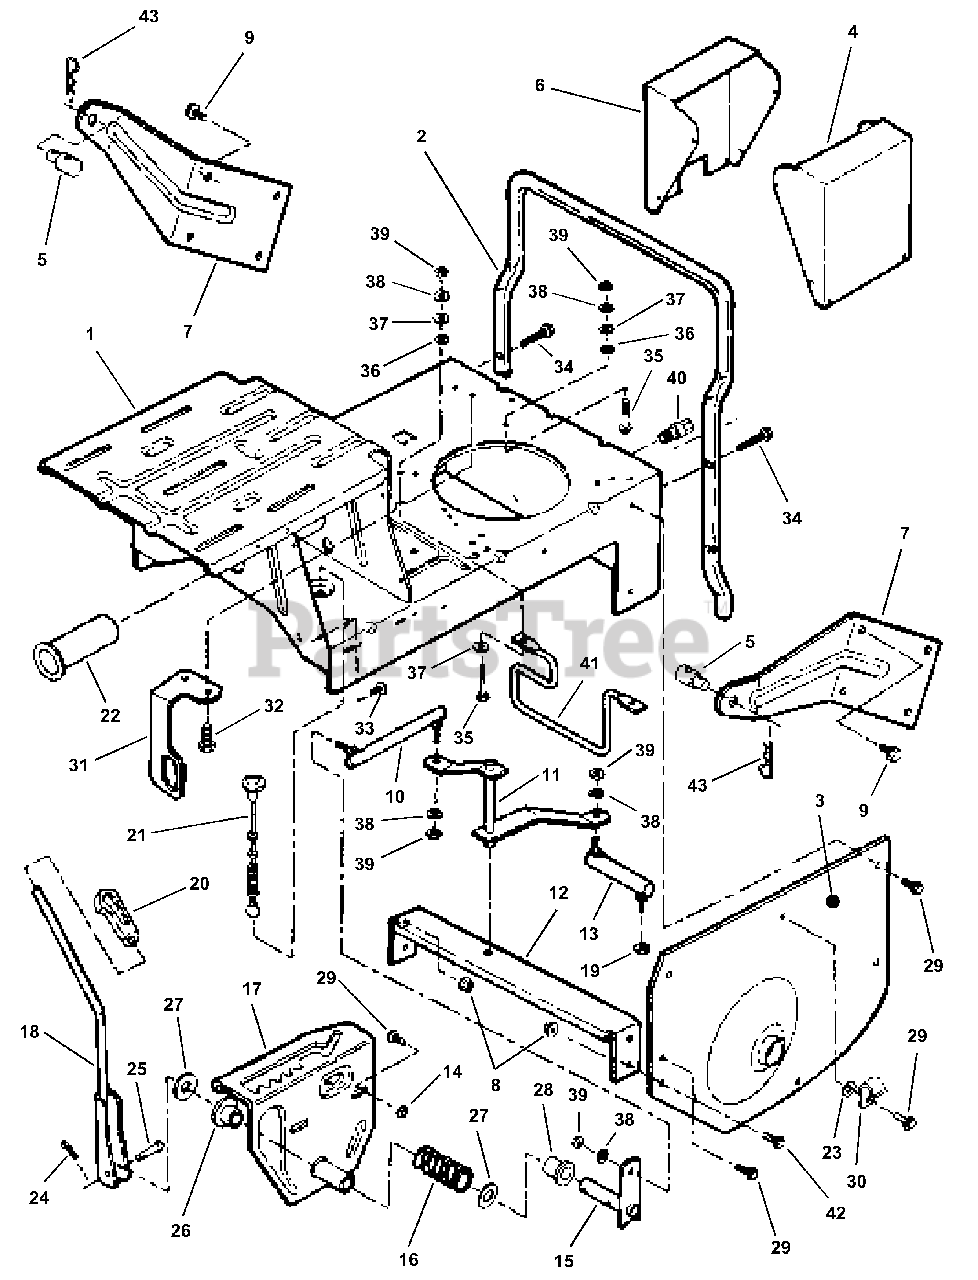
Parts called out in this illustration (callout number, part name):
1	CASE, Main (Standard) (8 & 10HP)
2	BUMPER, Rear
3	FENDER, Left Hand
4	COVER, Battery
5	SWIVEL
6	COVER, Switch
7	WING, Rear (Models 28" & 33" Only!)
8	NUT, 5/16-18 Hex Flange Lock
9	SCREW, 5/16-18 x 3/4" Self-Tapping
10	LINK, Shift (Long)
11	ARM, Shift
12	BRACE, Cross
13	LINK, Shift (Short)
14	NUT, 5/16-18 Hex
15	ARM, Shift Handle
16	SPRING, Shift Handle
17	DETENT, Shift
18	HANDLE, Shift
19	NUT, Hex Large Flange Lock 5/16-24
20	KNOB, Shift Handle
21	CABLE, Deck Support (5.5") (25" Models Only!)
22	BUSHING, Pilot
23	WASHER, 5/16 Internal Tooth Lock
24	COTTER-PIN, 3/32 x 3/4"
25	PIN, 1/4 x 1-3/4" Tapered Clevis
26	BUSHING, Nylon
27	WASHER, Thrust
28	BUSHING, Nylon
29	SCREW, 5/16-18 x 5/8" Self-Tapping
30	CLIP, Wire
31	BRACKET, Switch
32	SCREW, Self Tapping, 10-32 x 1/4"
33	FASTENER, 1/4x3/4 Ratchet (6)
34	SCREW, 5/16-18 x 1-1/2" Self-Tapping
35	SCREW, 5/16-24 x 1-3/4" Hex Head Cap
36	RETAINER, 5/16 Bolt
37	WASHER, 5/16" Flat
38	WASHER, 5/16" Split Lock
39	NUT, 5/16-24 Hex
40	DRAIN, Oil (Short)
41	GUIDE, Belt (25" Models)
42	SCREW, 5/16-18 x 3/4" Hex Cap
43	HAIRPIN, 3/32 x 1-1/2"
